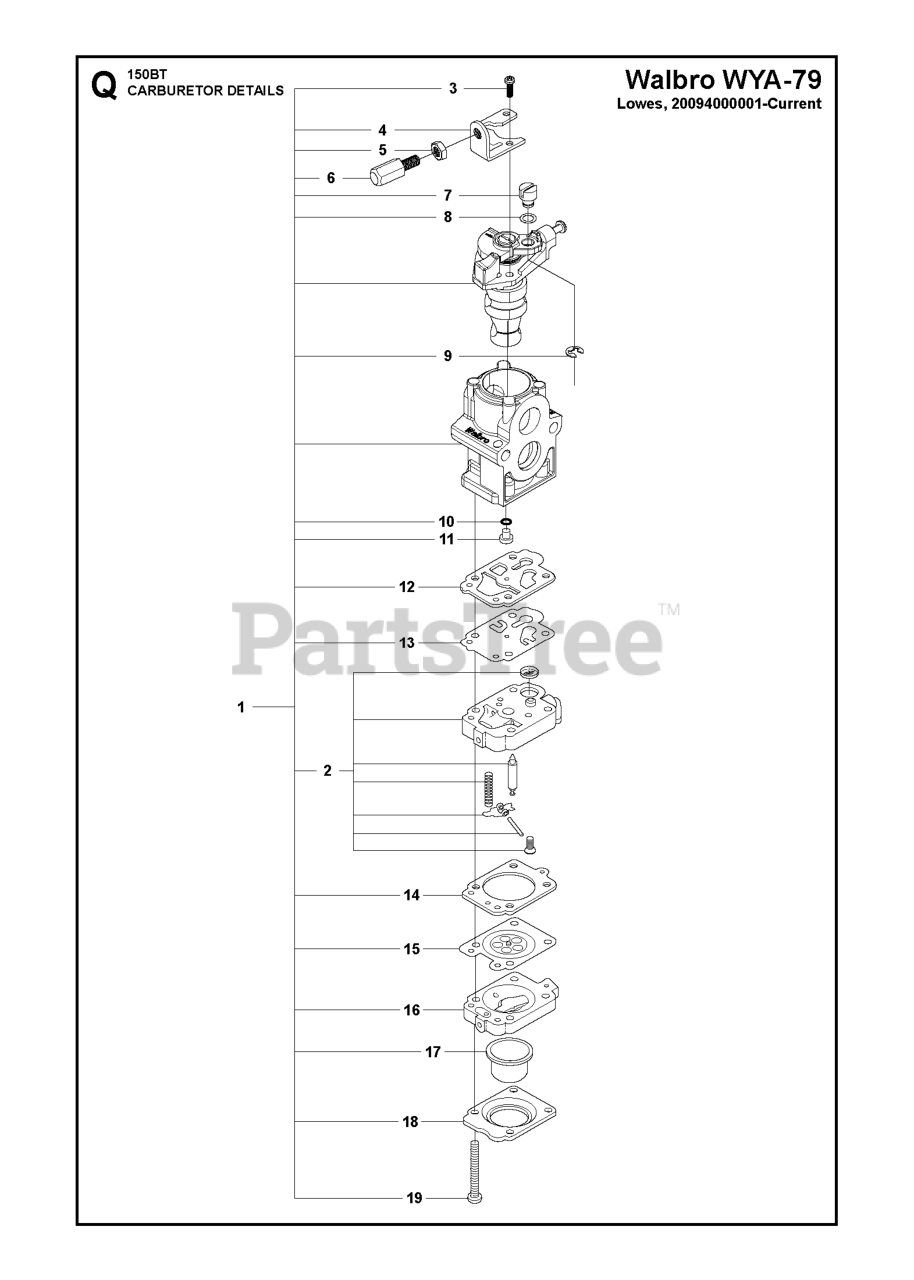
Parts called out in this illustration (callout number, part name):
1	CARBURETOR
2	BODY-A-PUMP
5	NUT
6	ADJUSTER
11	JET
